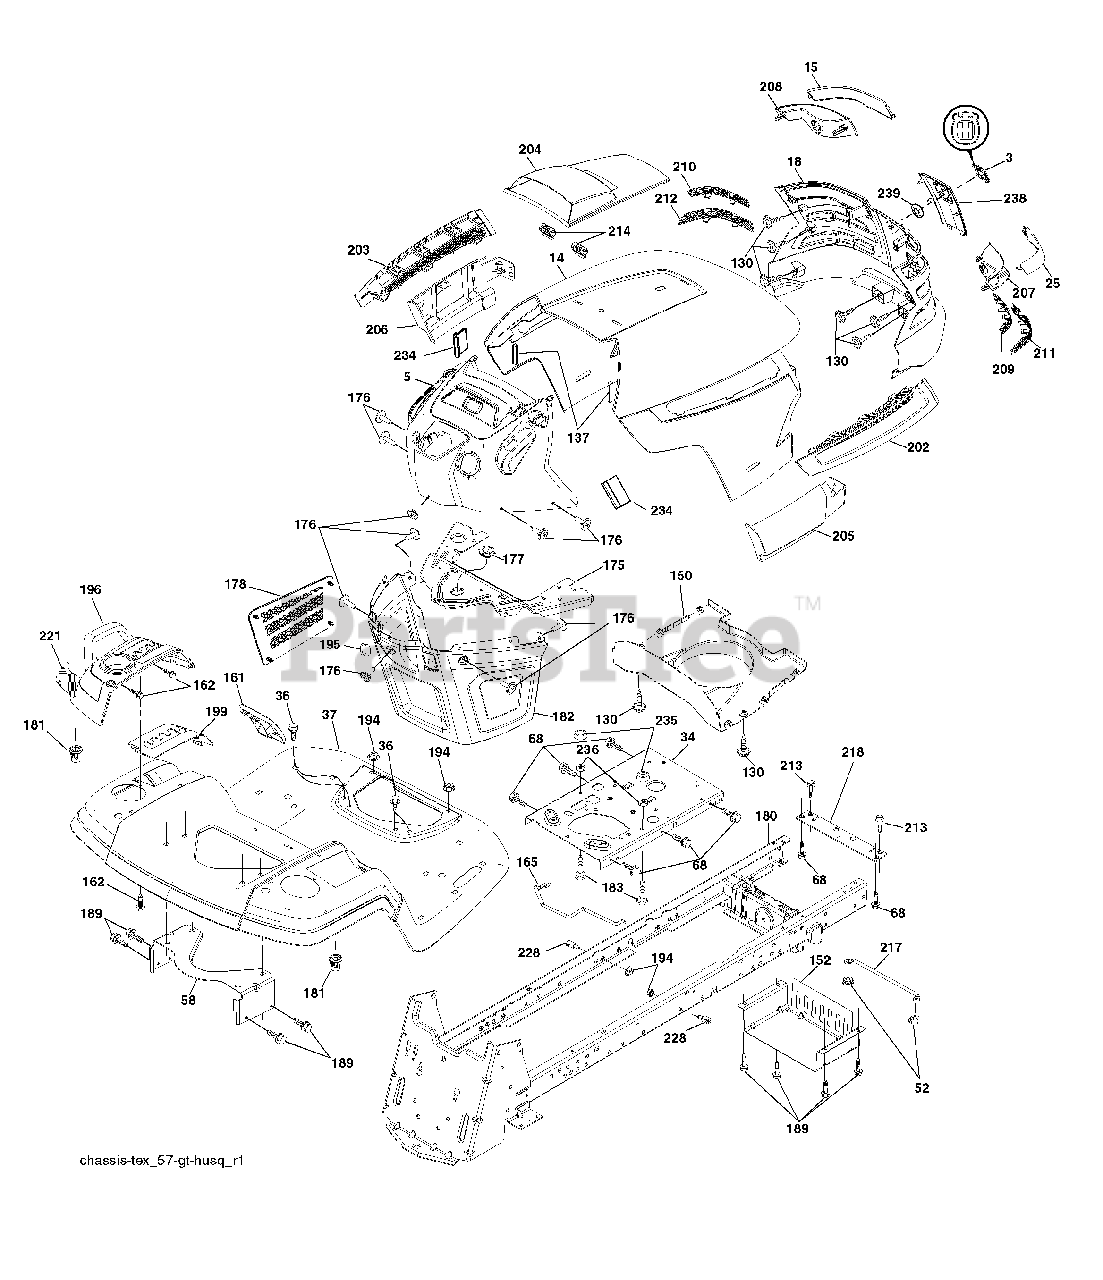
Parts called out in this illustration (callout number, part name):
3	Logo Husq.
14	Hood
34	Plate Engine
36	Screw 5/16-18 x 3/4
37	Fender
52	Nut Crown Lock 5/16-18
58	Bracket Fender
68	Screw 5/16-18 x 1/2
130	Screw #10 x 0.750 BOS Thread
137	Bumper Dash
150	Duct Heat Hood
152	Shield Browning/Debris
161	Console Fuel Window
162	Screw Hex Wsh HiLo 1/4 x 1/2
165	Bracket Support Tank
175	Crossmember
176	Screw 10-24 x 5/8 Wshd Qdrx
177	Bushing Steering
178	Cargo Asm. Net
180	Chassis
181	Bushing Mtg. Fender Crgo.
182	Dash Lower
183	Bolt Fin Hex 5/16-18 unc x 1-1/4
189	Screw 5/16-18 x 3/4
194	Nut Lock Hex Flange 5/16-18
195	Plug Cruise/Phone
196	Console Asm.Deck Lift
199	Plate Deck Lift
202	Vent Side Hood RH
203	Vent Side Hood LH
204	Vent Asm Hood Top
205	Skirt Hood Side RH
206	Skirt Hood Side LH
209	Insert Hex Top RH
210	Insert Hex Top LH
211	Insert Hex Bottom RH
212	Insert Hex Bottom LH
213	Bolt Hex HD 5/16-18 unc x 3/4
214	Clip Retainer
221	Reflector LH
228	Stud Fastener
234	Bumper Hood
235	Spacer Fender
236	Nut Center Lock 5/16-18 unc
238	Trim Husq.
